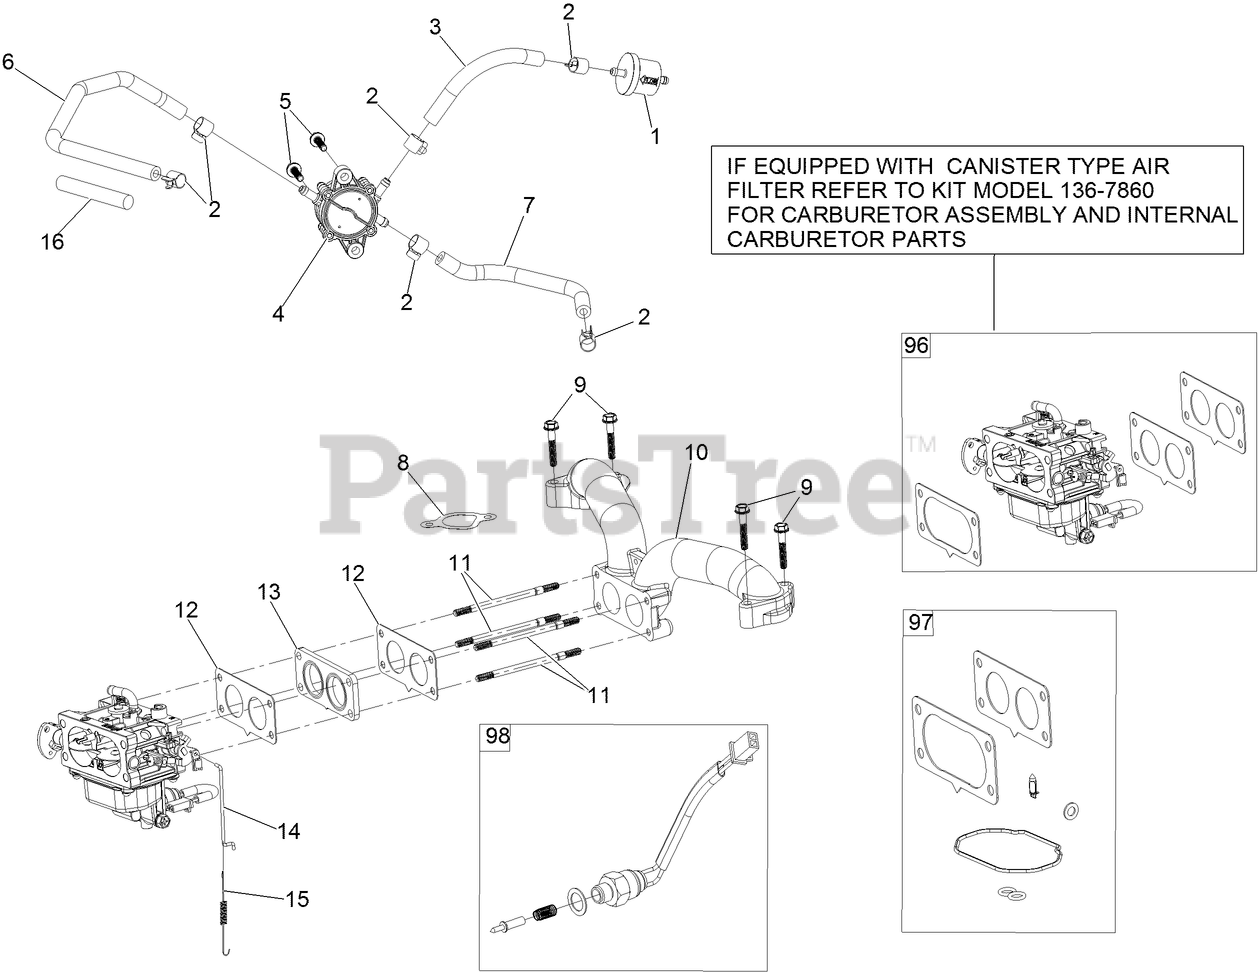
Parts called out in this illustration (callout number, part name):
1	FILTER-FUEL
2	CLAMP-FUEL HOSE
3	LINE-FUEL
4	PUMP-FUEL
5	SCREW-HHF
6	HOSE-FUEL
7	HOSE-FUEL
8	GASKET-INTAKE
9	SCREW-HHF
10	MANIFOLD-INTAKE
12	GASKET-CARBURETOR
13	INSULATOR-CARBURETOR
14	LINKAGE-THROTTLE
15	SPRING-RETURN, THROTTLE
16	SLEEVE-FUEL LINE PROTECTO
96	CARBURETOR REPLACEMENT KI
97	CARBURETOR REPAIR KIT
98	SOLENOID KIT
